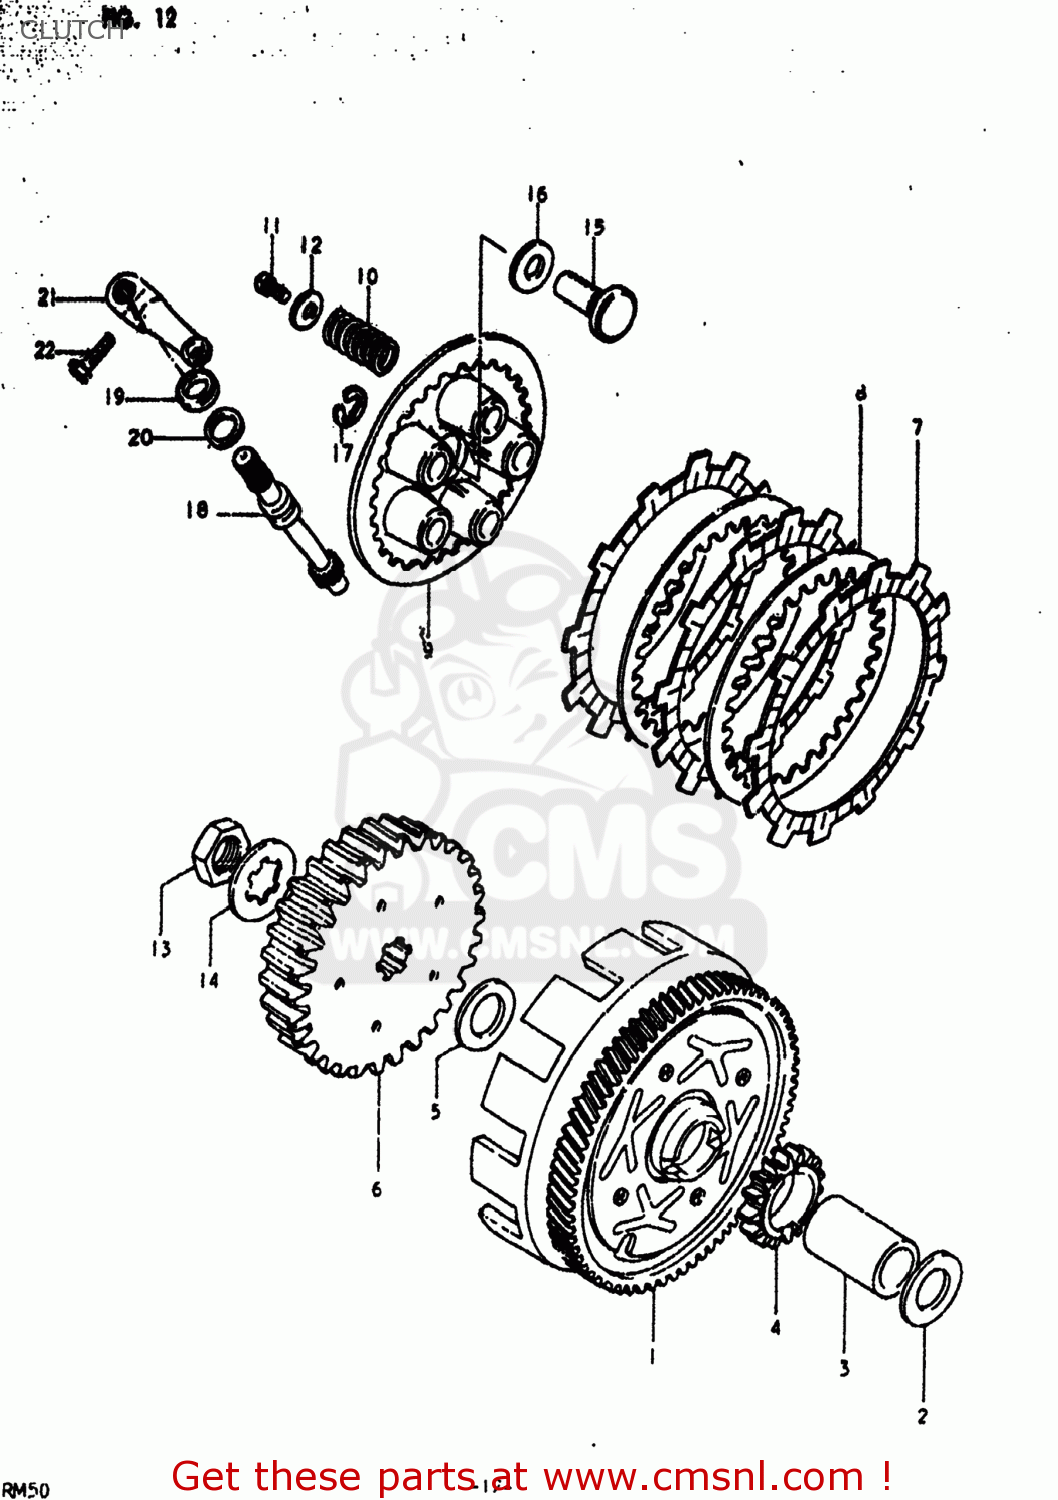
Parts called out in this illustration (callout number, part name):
1	GEAR ASSEMBLY,PRIMARY DRIVE
2	WASHER,THRUST
3	SPACER
4	GEAR,KICK STARTER DRIVE
5	WASHER
6	HUB,CLUTCH SLEEVE
7	PLATE,CLUTCH DRIVE
8	PLATE,CLUTCH DRIVEN (NAS)
9	DISC,CLUTCH PRESSURE
10	SPRING
11	BOLT(5X16)
12	WASHER (5.5X16X1.2)
13	NUT
14	WASHER,LOCK
15	RACK,CLUTCH RELEASE
16	BEARING(10X22X2.8)
17	E RING 8MM
18	PINION,CLUTCH RELEASE
19	OIL SEAL
20	WASHER (12X17X1)
21	ARM,CLUTCH RELEASE
22	BOLT, UPPER
